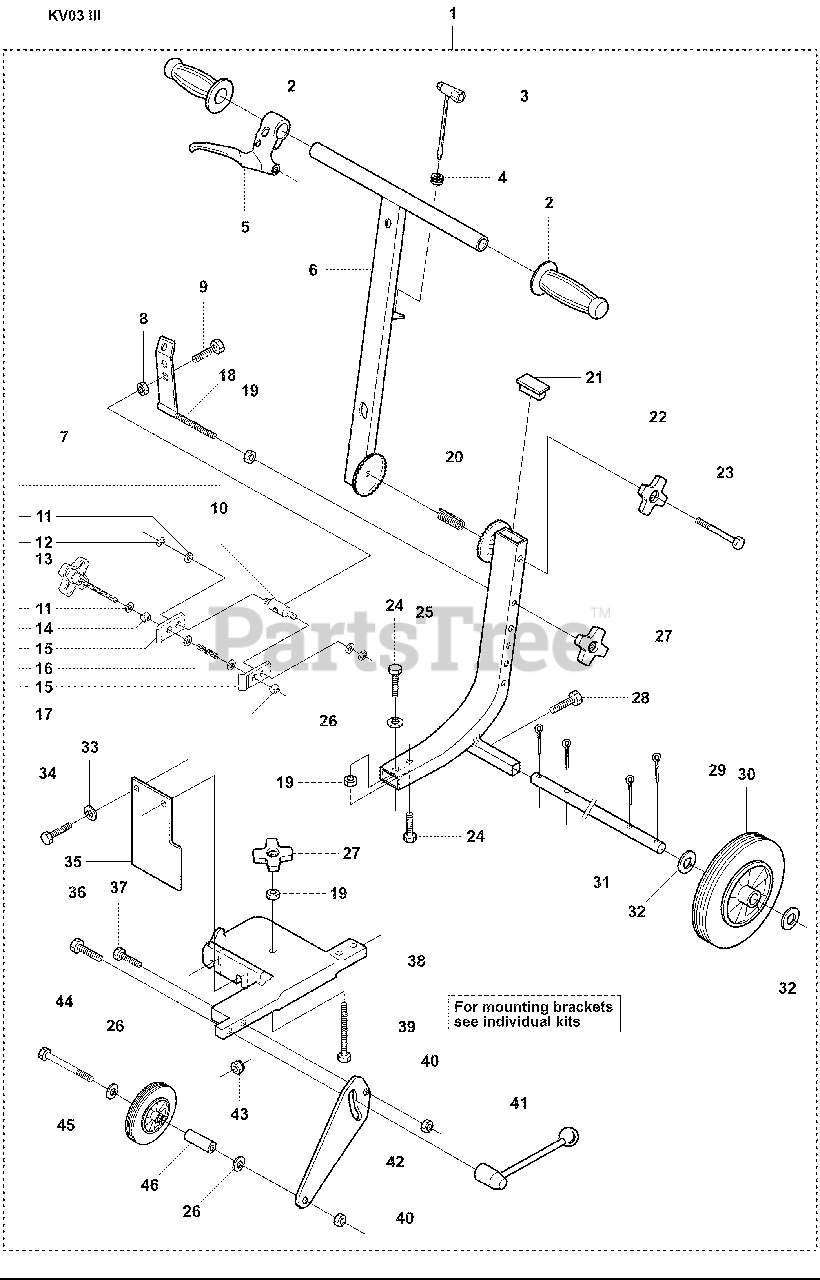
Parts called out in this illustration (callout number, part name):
1	CUTTING TROLLEY
3	COMBINATION TOOL
4	ANTIVIBE ELEMENT
5	THROTTLE HANDLE
7	BRACKET
8	MUTTER M10 FZ
13	STEERING WHEEL
16	COMPRESSION SPRING
19	NUT
20	COMPRESSION SPRING
22	STEERING WHEEL
25	FRAME TUBE
27	STEERING WHEEL
35	SPRAY GUARD
46	SPACING SLEEVE
